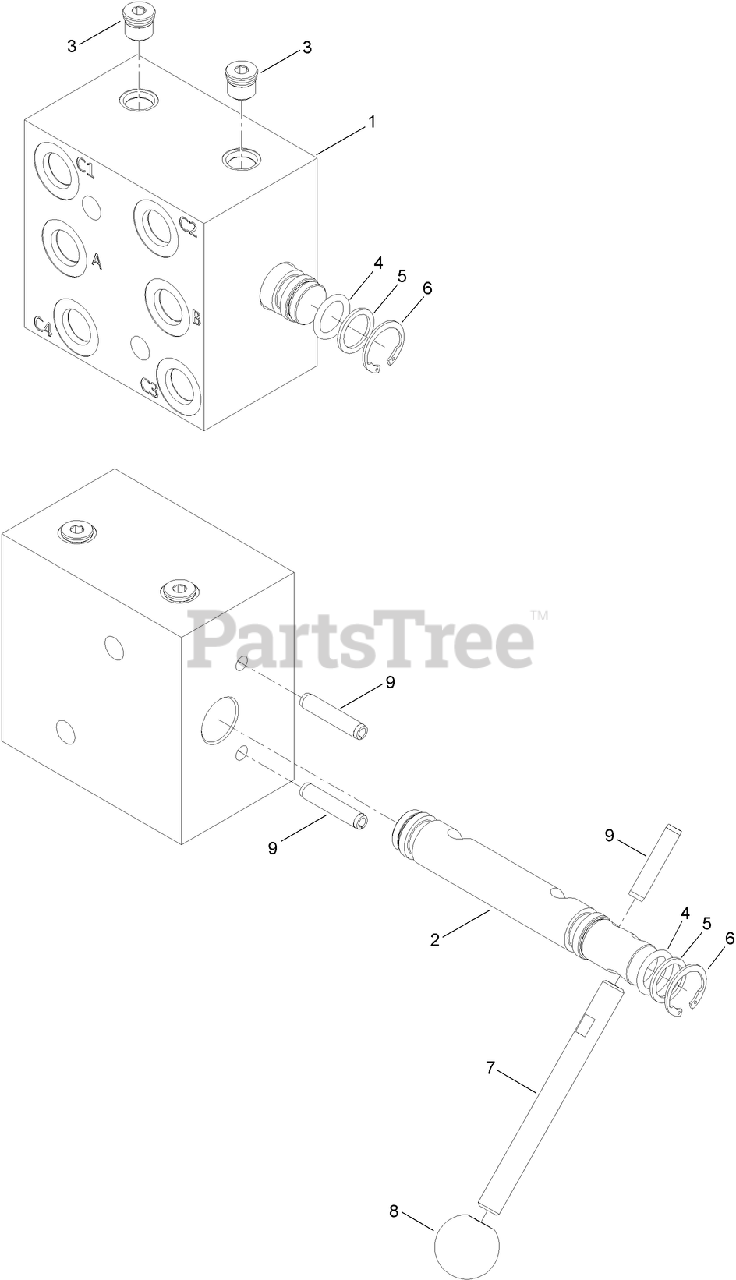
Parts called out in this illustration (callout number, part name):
1	BLOCK-MANIFOLD
2	SPOOL-SELECTOR
3	Plug
4	O-RING
5	RING-BACK UP
6	RING-RETAINING
7	HANDLE-SPOOL, LONG
8	KNOB-BALL, PLASTIC
9	PIN-SPRING
